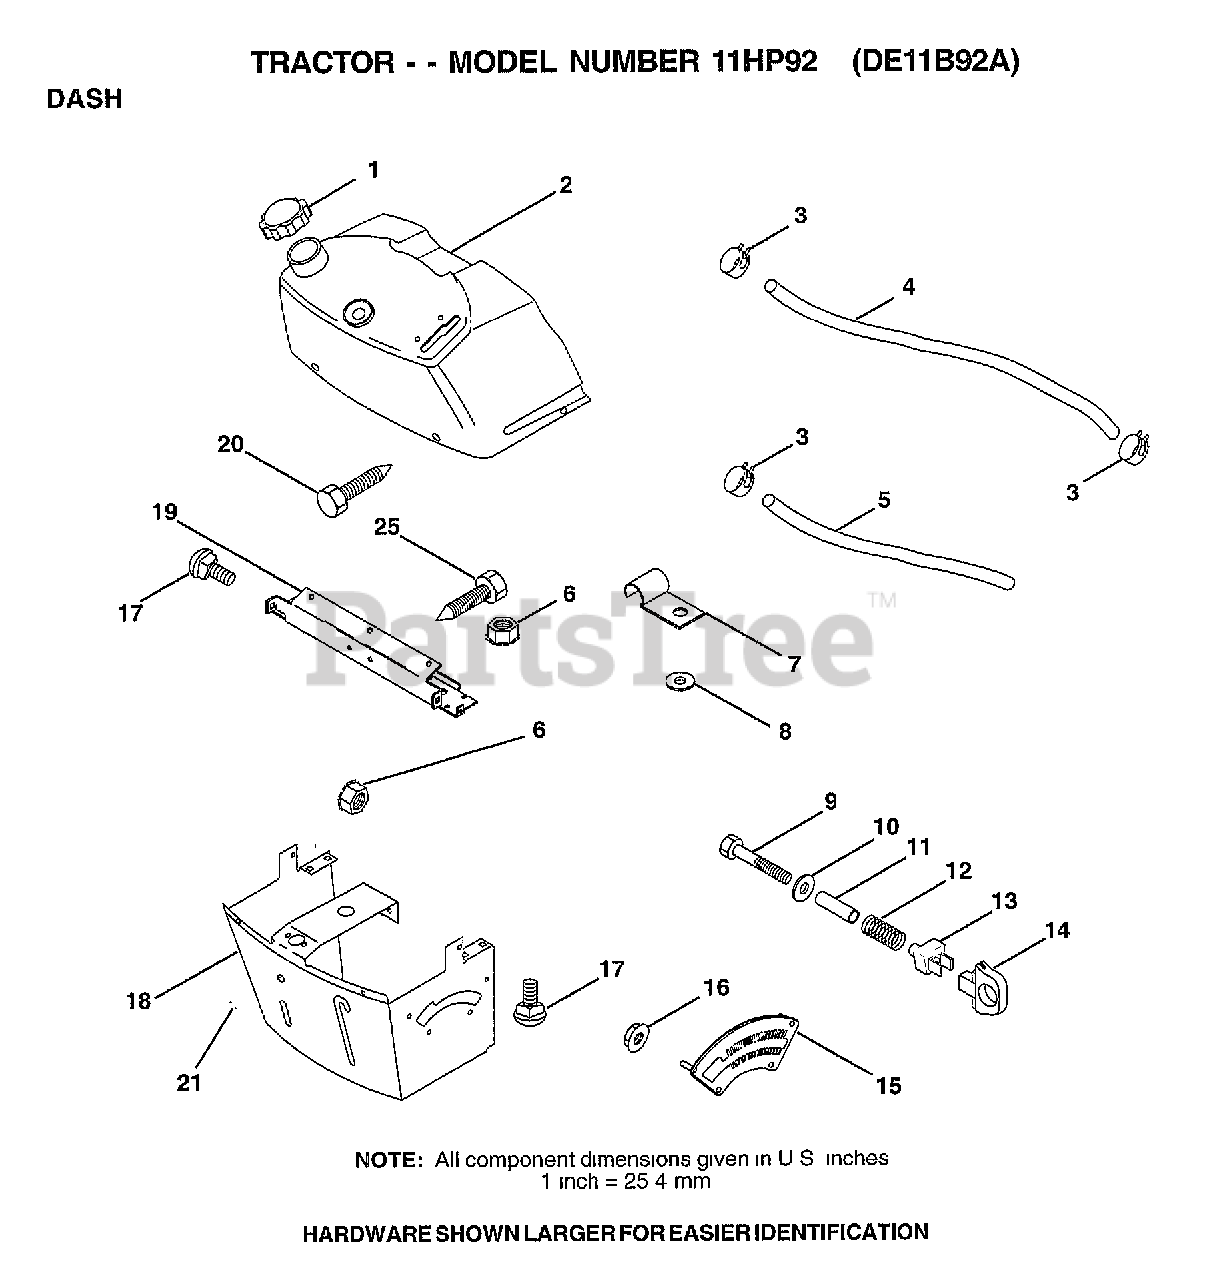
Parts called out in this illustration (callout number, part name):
1	CAP BLK FUEL LR
2	TANK.ASM.DASH.LR
3	HOSE CLAMP
5	FUEL LINE T
6	NUT HXKEP 1/4X20
7	CLIP T
8	WASHER PM
9	BOLT
11	SPACER SPLIT
12	SPRING M
13	"KNOB,HGT RETAINER"
14	KNOB
15	ADJUSTER QUAD
16	NUT
17	BOLT
18	SUPT ASSY DASH
19	CROSS BRACE
20	SCREW.1/4-20X1/2
21	PLUG DOME
25	SCREW LT
